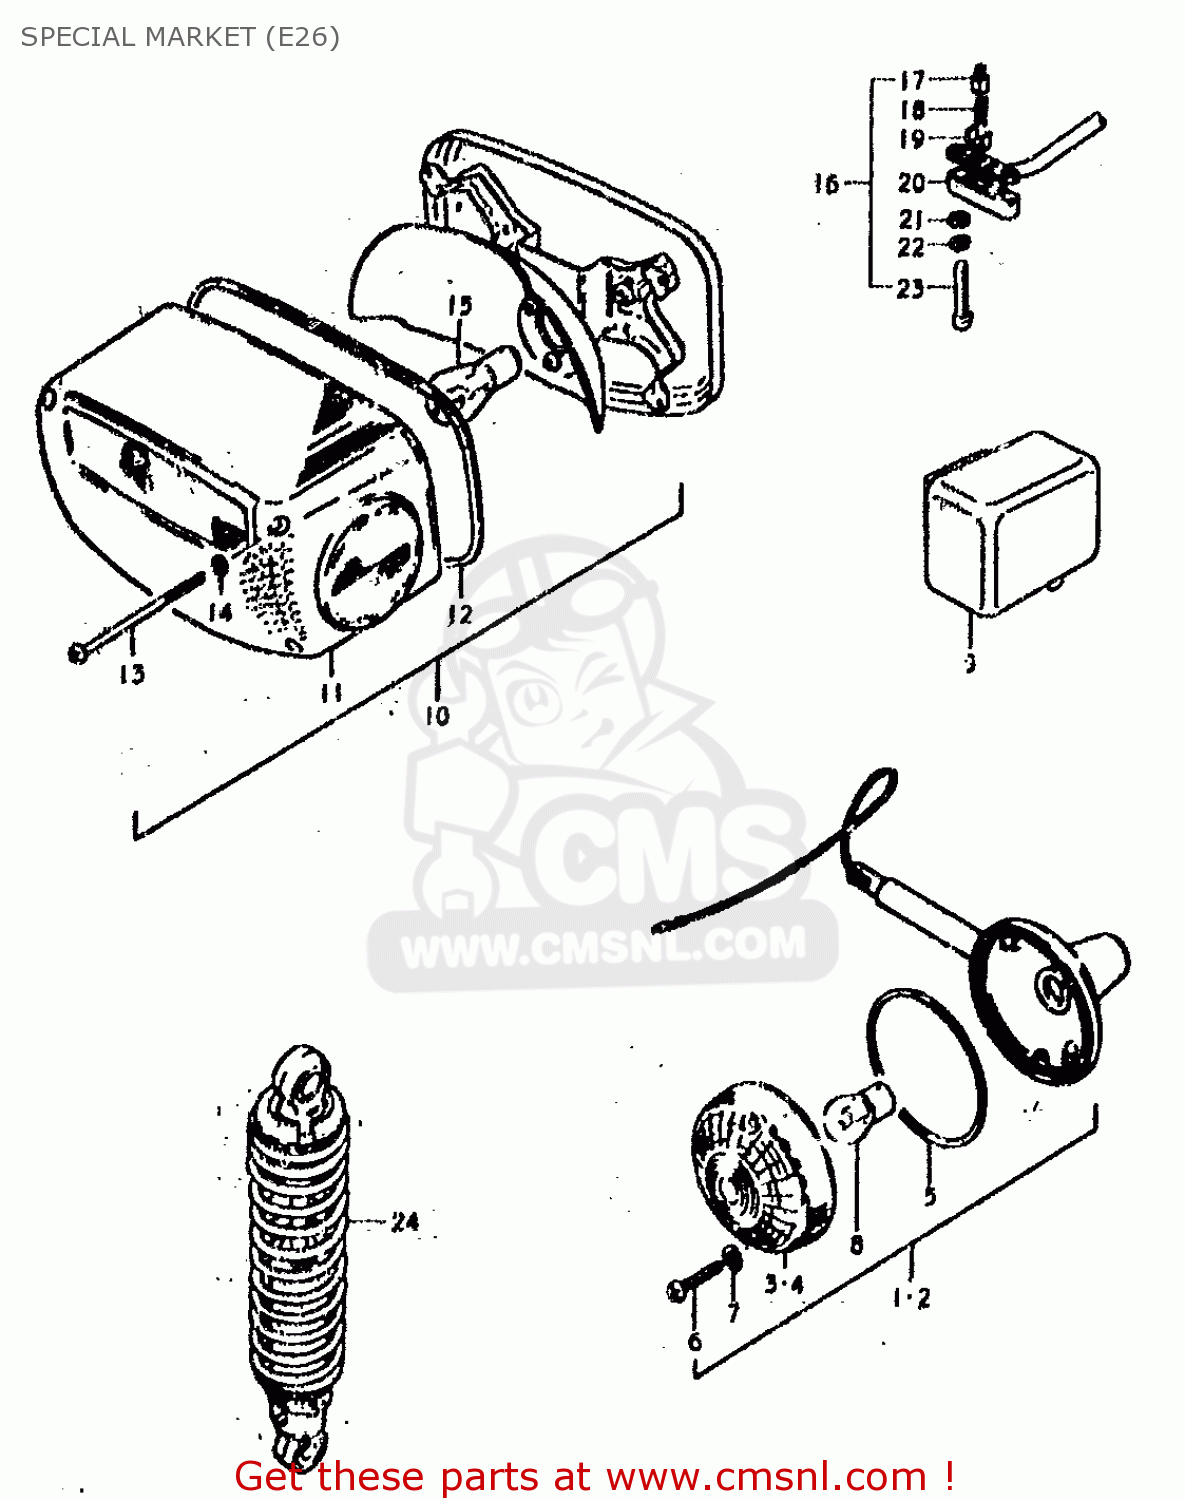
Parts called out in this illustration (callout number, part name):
1	LAMP ASSY, FRONT TURN SIGNAL
2	LAMP ASSY, REAR TURN SIGNAL
3	LENS
4	LENS
5	GASKET (NAS)
6	SCREW
7	GASKET (NAS)
8	BULB 12V 21W
10	LAMP ASSY, REAL COMBINATION
11	LENS,REAR COMBINATION LAMP
12	GASKET (NAS)
13	SCREW (4X55)
14	GASKET (NAS)
15	BULB
16	SWITCH ASSY,STOP
17	HOLDER
18	SPRING
19	PLATE
20	COVER,FR BK TERMINAL BASE
21	WASHER
22	LOCK WASHER
23	SCREW
24	SHOCK ABSORBER,REAR
